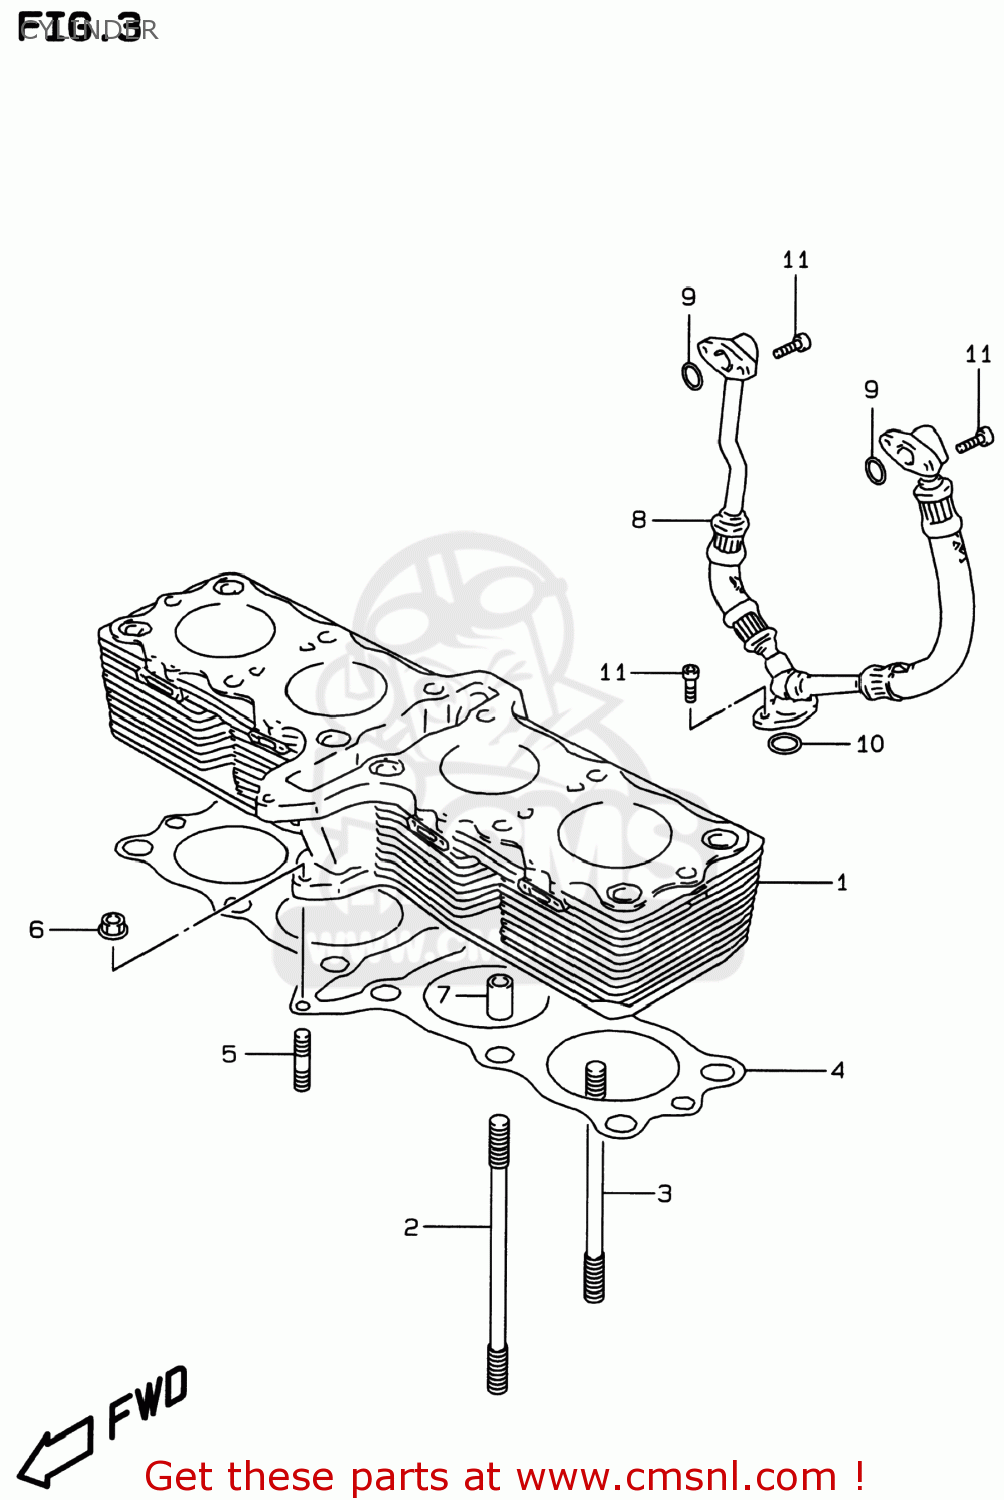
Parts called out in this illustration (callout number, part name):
1	CYLINDER COMP
2	STUD BOLT (L:150)
3	BOLT,STUD
4	GASKET,CYLINDER (NAS)
5	STUD,M6X1X32
6	NUT
7	PIN
8	HOSE,OIL HEAD COOLER
9	O RING(D:2.5,ID:13.8)
10	O RING(D:2.4,ID:15.8)
11	BOLT,OIL FILLE
